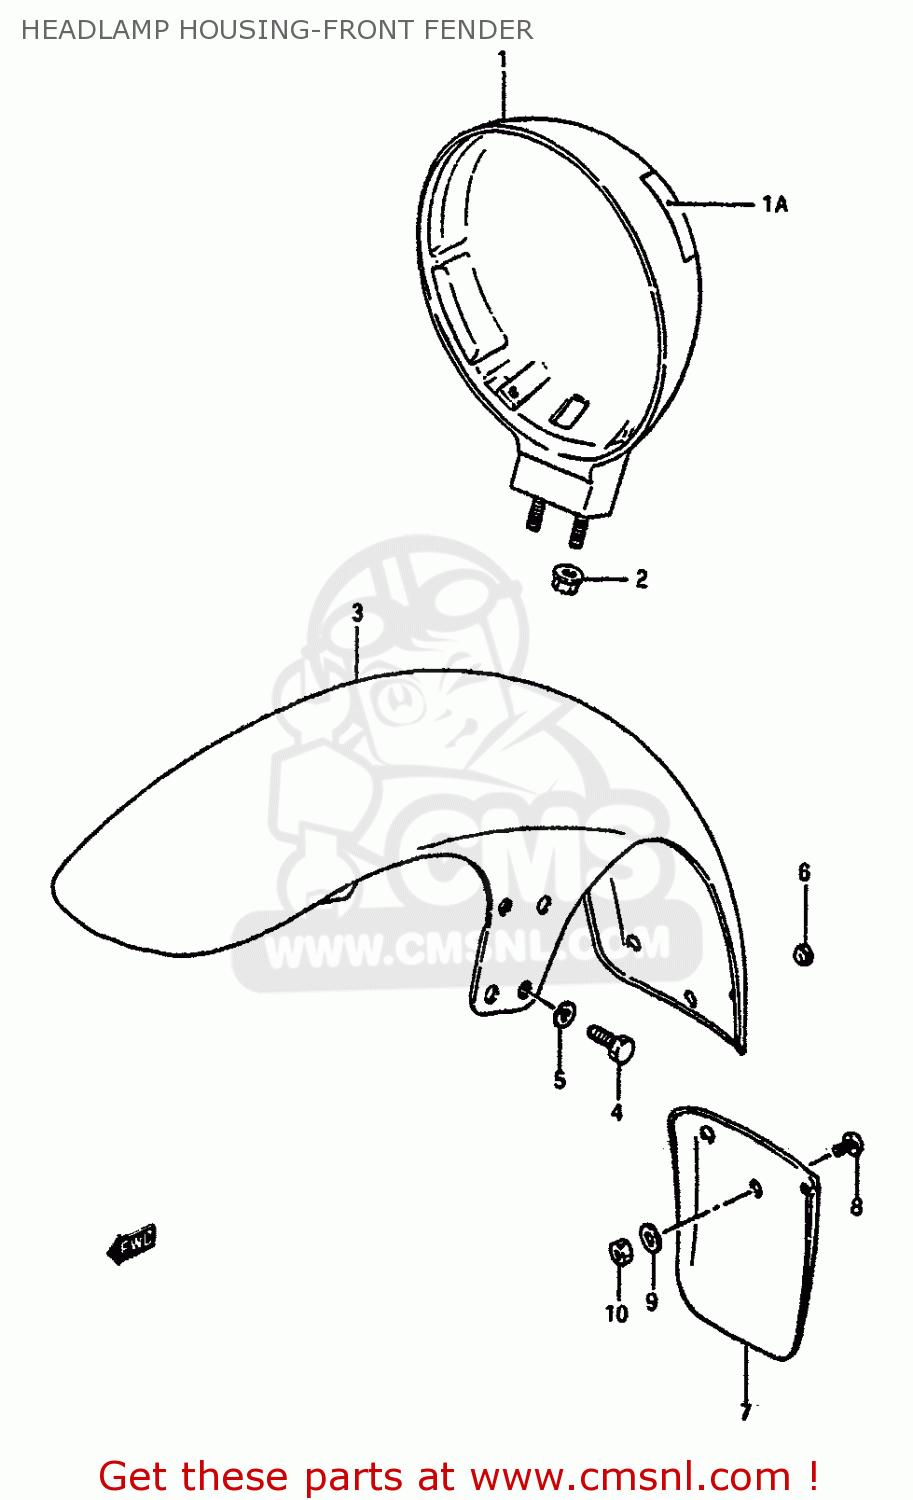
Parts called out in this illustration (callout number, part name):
1	HOUSING,HEADLAMP
1A	TAPE,FRAME HEAD COVER
2	NUT
3	FENDER,FRONT
4	BOLT
5	WASHER,LOCK
6	CAP(OD:10)
7	EXTENSION
8	SCREW
9	WASHER,5MM
10	NUT 5MM
